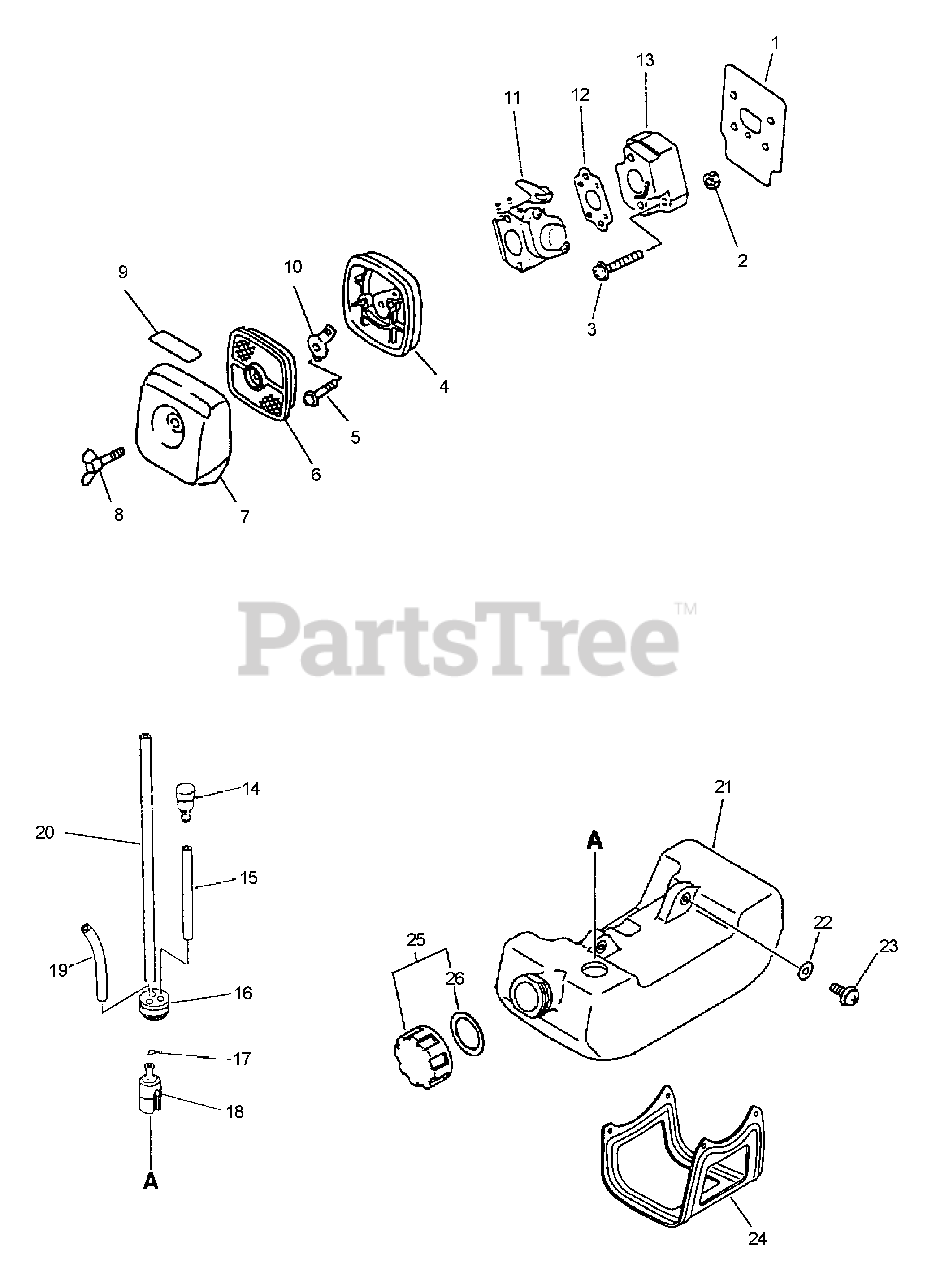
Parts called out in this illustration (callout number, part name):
1	SHIELD, INTAKE
3	SCREW - 5X20
4	AIR FILTER CASE ASSY
5	SCREW - 5X65
6	FILTER, AIR - SINGLE LAYER
7	COVER, AIR FILTER - BLACK
8	THUMBSCREW
9	LABEL - CHOKE
10	PLATE, PREVENT
11	CARBURETOR WT-424B
12	GASKET, INTAKE
13	INSULATOR, INTAKE
14	VENT, FUEL TANK
15	PIPE - 3X5X70 -- BLACK
16	GROMMET
17	CLIP - 6
18	FILTER, FUEL
19	PIPE - 3X6X90 -- CLEAR
20	PIPE - 3X5X180 -- BLACK
21	FUEL TANK ASSY
22	WASHER - 5
23	SCREW - 5X16
24	GUARD, FUEL TANK
25	CAP ASSY
26	GASKET, CAP
